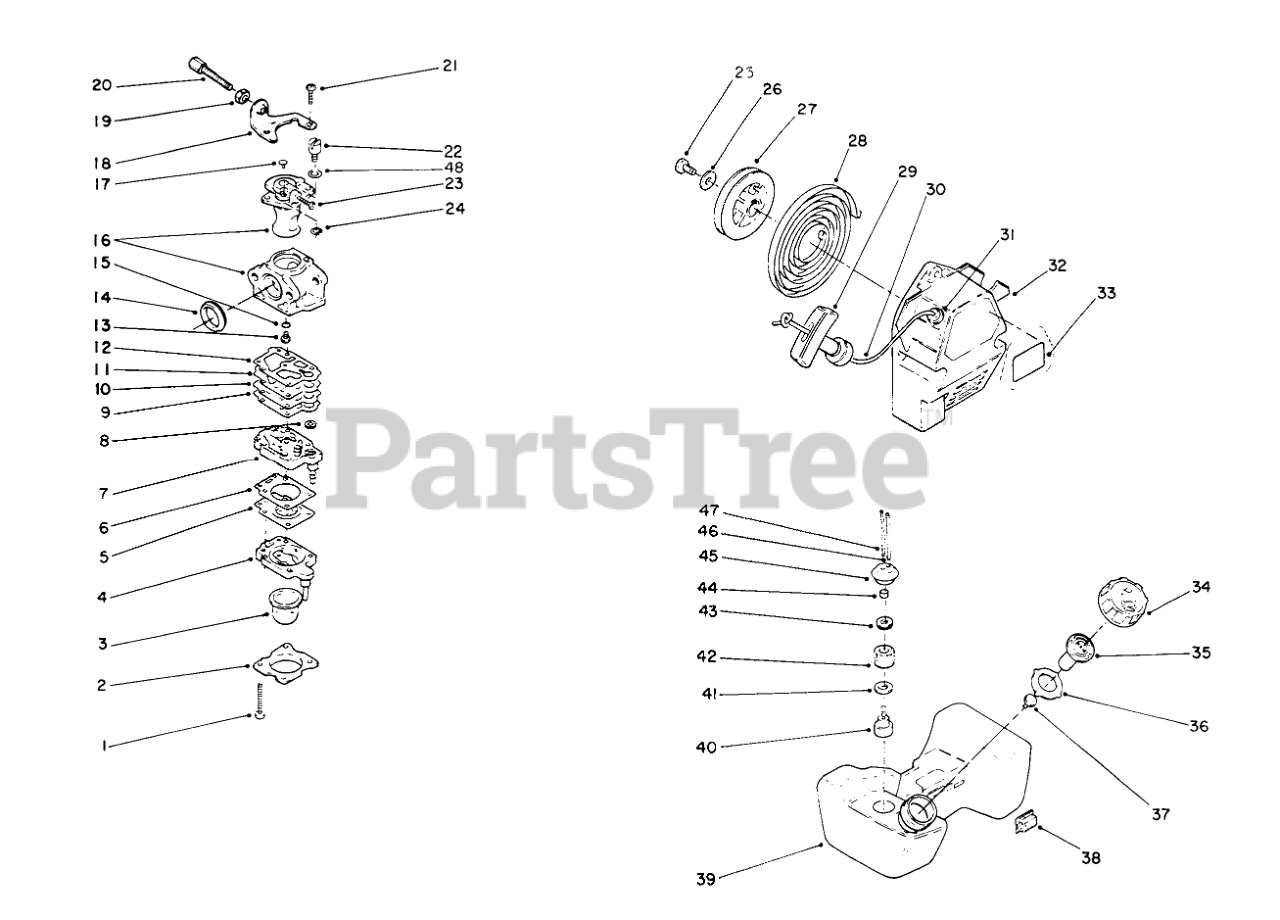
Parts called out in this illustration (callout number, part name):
1	SCREW
2	Cover-Primer
3	PRIMER PUMP
4	PRIMER BODY
5	DIAPHRAGM
6	DIAPHRAGM GASKET
7	Body Ass-y-Pump (Incl. Ref. #8)
8	SCREEN
9	PUMP GASKET
10	Plate
11	DIAPHRAGM
12	DIAPHRAM GASKET
13	MAIN JET
14	RUBBER CARB GASKET
15	MAIN JET O-RING
16	Body-Carburetor (Ref.)
18	BRACKET
19	LOCKNUT
20	ADJUSTING SCREW
21	SCREW
22	Holder-Wire
23	THROTTLE VALVE
25	SCREW
26	WASHER
28	SPRING
29	Knob-Starter
30	Rope-Recoil
31	GUIDE
32	RECOIL CASE
33	Decal-Toro
34	FUEL TANK CAP
35	BREATHER VALVE
36	PACKING
39	Tank Assembly-Fuel (Incl. Ref. #34-37 & 40-47)
40	Weight-Filter
42	Filter-Fuel
43	Washer-Seal
44	COLLAR
45	FUEL TANK GROMMET
46	TUBE, FUEL
47	RETURN FUEL HOSE
48	WASHER
